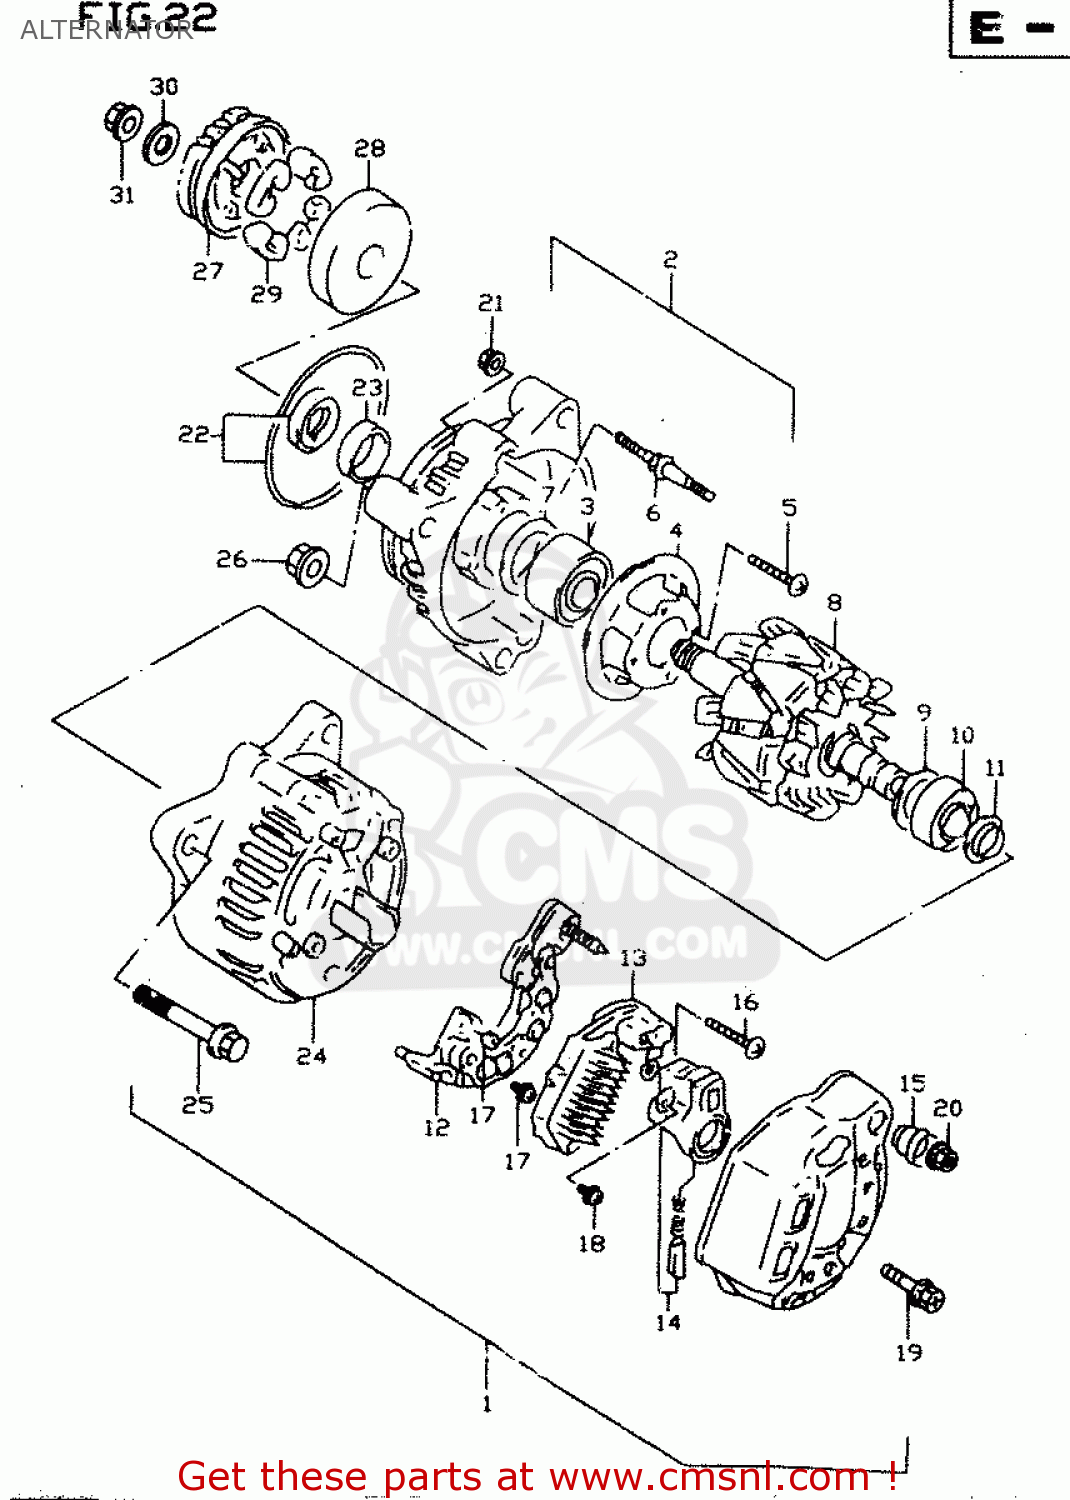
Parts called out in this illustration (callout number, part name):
1	ALTERNATOR ASS
2	FRAME,DRIVE END
3	BEARING
4	RETAINER
5	SCREW(4X14)
6	STUD BOLT
7	COVER,BEARING
8	ROTOR ASSY
9	COVER,BEARING
10	BEARING
11	COVER(2)
12	HOLDER,RECTIFIER
13	REGULATOR ASSEMBLY
14	HOLDER,BRUSH
15	INSULATOR,TERMINAL
16	SCREW
17	SCREW 4X6
18	SCREW
19	SCREW
20	NUT
21	NUT
22	SERVICE KIT(A)
23	SPACER
24	FRAME,END
25	BOLT
26	NUT
27	GEAR,GENERATOR DRIVEN
28	HOUSING,GENERATOR GEAR DAMPER
29	DAMPER,GENERATOR DRIVEN
30	WASHER
31	NUT
